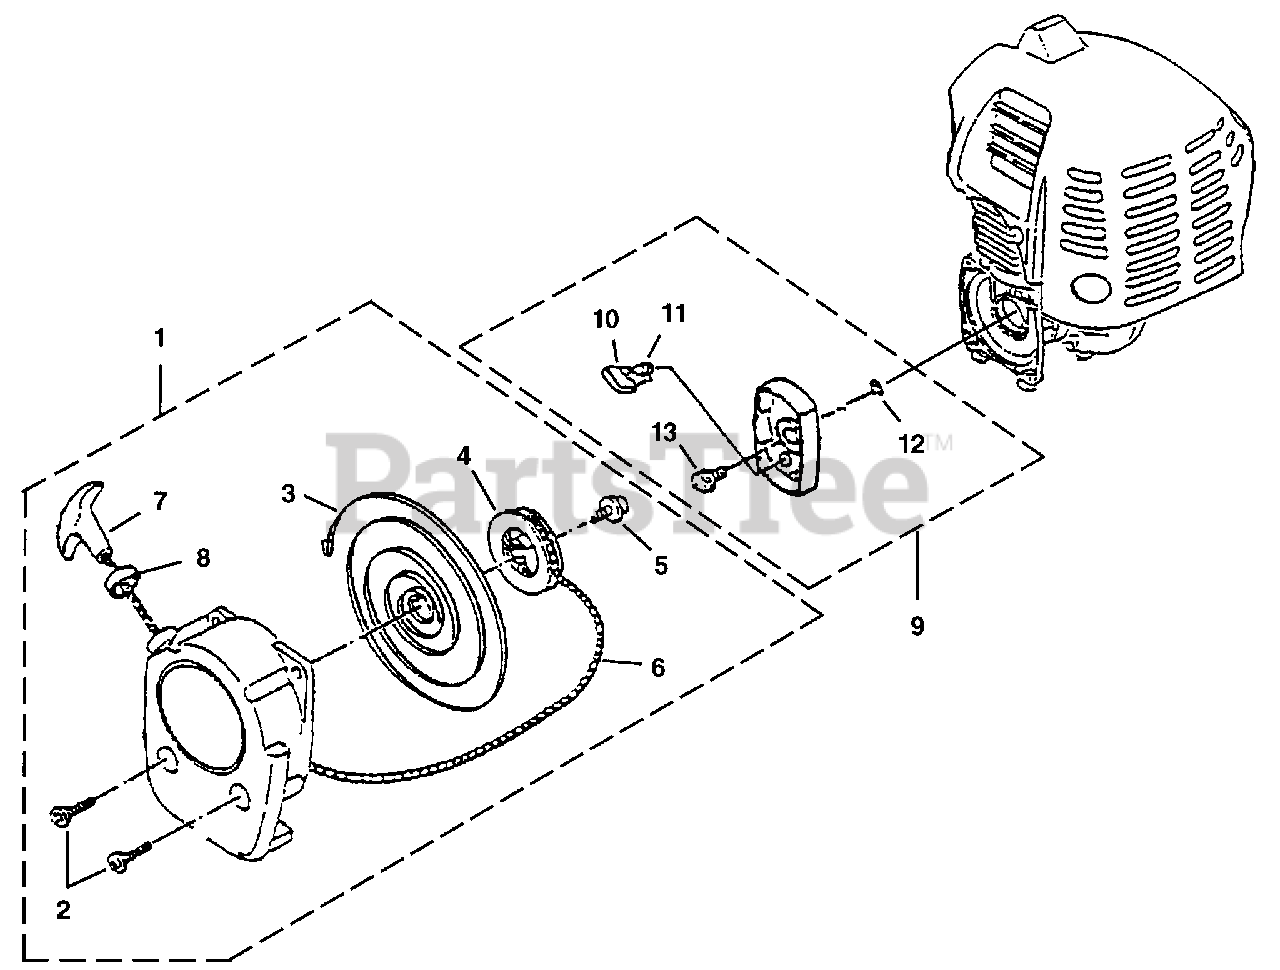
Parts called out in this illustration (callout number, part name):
1	STARTER COMPLETE
2	SCREW-Socket Hd (M5 x 30)
5	SCREW-Set (M5 x 30)
6	ROPE-Starter
8	DAMPER-Grip
9	STARTER CUP ASSEMBLY
11	SPRING-Return
13	BOLT ASSEMBLY (M6 x 16)
